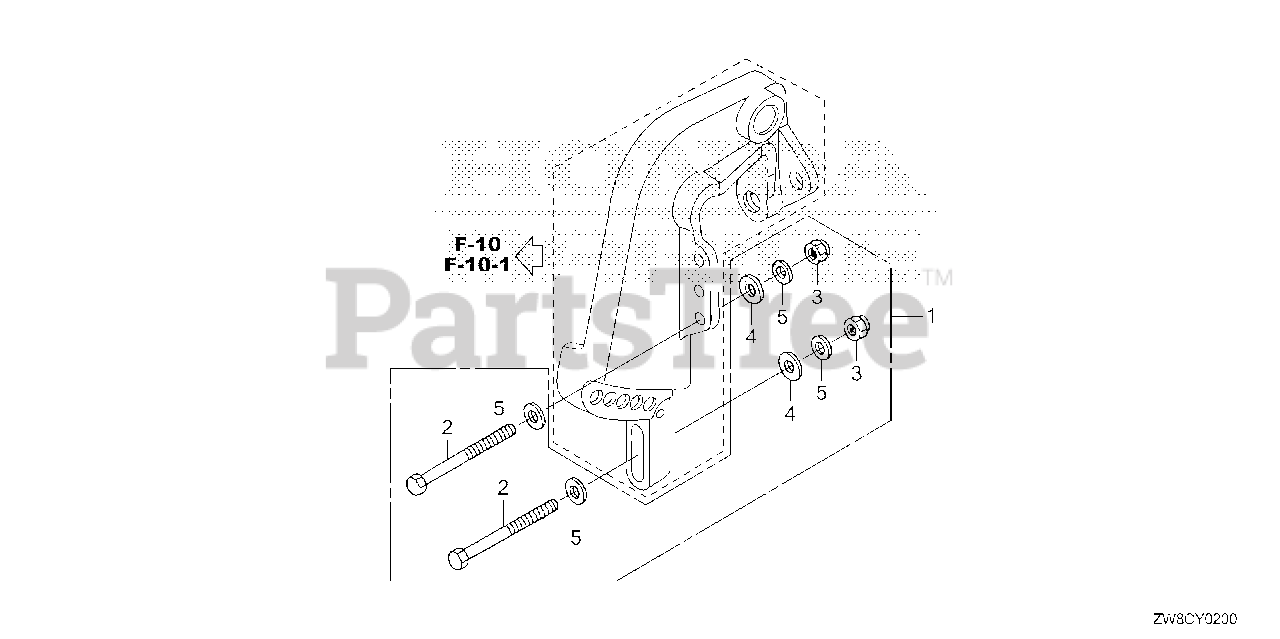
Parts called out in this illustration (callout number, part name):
1	INSTALLATION KIT, OUTBOARD
2	BOLT, HEX. (10X100)
3	NUT, SELF-LOCK (10MM)
4	WASHER, PLAIN (10MM)
5	WASHER, PLAIN (10MM)
